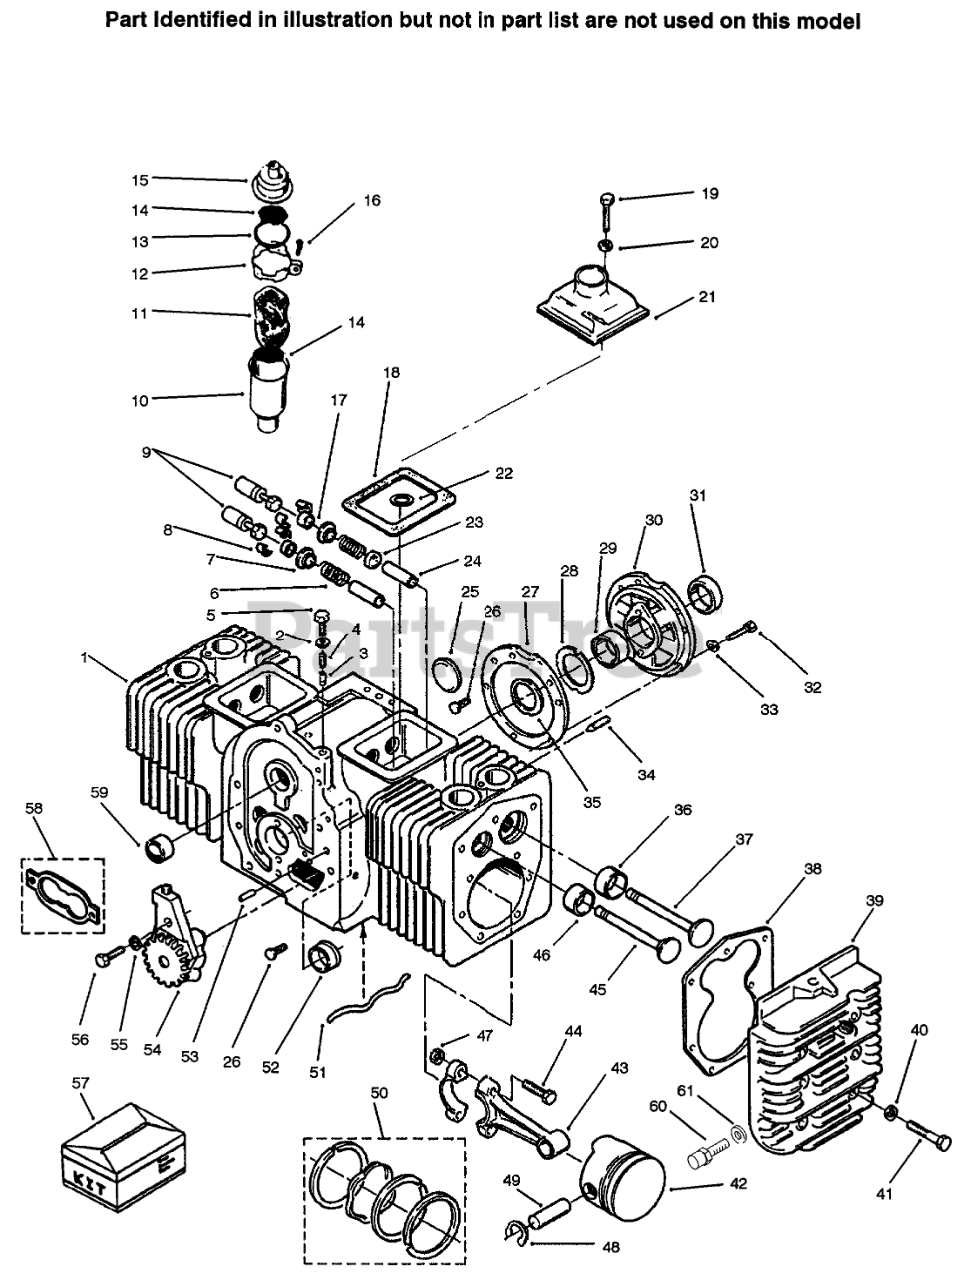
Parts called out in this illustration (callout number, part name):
1	CYLINDER BLOCK
2	WASHER
3	PLUNGER
4	SPRING
5	SCREW-HH
6	VALVE SPRING
7	VALVE SPRING RETAINER
8	VALVE SPRING LOCK
9	TAPPET
9	TAPPET .002 OS
10	TUBE-BREATHER
11	FILTER
12	Clamp
13	SEAL - O-RING
14	SCREEN-BREATHER TUBE
15	BREATHER-CAP AND VALVE
16	SCREW-TAPPING, ROUND HEAD
17	VALVE CAP
18	GASKET
19	HHCS 1/4-20 X 1 3/4
20	WASHER
21	VALVE-COVER L.H.
22	WASHER-FLAT
23	VALVE STEM SEAL
24	EXHAUST VALVE GUIDE
24	INTAKE VALVE GUIDE
26	PIN-DRIVE
27	GASKET
29	BEARING KIT (STANDARD SLEEVE)
29	BEARING KIT (.010)
29	BEARING-CRANKSHAFT (.002)
29	BEARING-CRANKSHAFT (.020)
29	BEARING-CRANKSHAFT (.030)
30	PLATE-BEARING, REAR
32	HEX HD CAPSCREW
33	WASHER-LOCK
33	WASHER-FLAT
34	SCREW-SET
35	WASHER
36	STD INSERT
36	INSERT .010
37	INTAKE VALVE
38	GASKET
39	CYL RS HEAD
39	LH CYLINDER HEAD
40	WASHER
41	Screw-HH
42	STD PISTON KIT
42	PISTON .010
42	PISTON .020
42	PISTON .030
43	CONN ROD ASM
43	ROD .03 US
45	EXHAUST VALVE
46	STD INSERT
46	INSERT .002
46	INSERT .005
46	INSERT .010
46	.025" Oversize
48	Piston Pin
49	PISTON PIN
50	RING/PISTON KIT
50	RING/PISTON KIT .050
50	RING/PISTON KIT .010
50	RING/PISTON KIT .020
50	RING/PISTON KIT .030
51	OIL TUBE
52	KIT-BEARING, SLEEVE
52	BEARING KIT (.010)
52	BEARING-CRANKSHAFT
53	PIN-GEAR COVER
55	WASHER-FLAT
56	SCREW - CAP HEX HEAD
57	ENGINE GASKET KIT
58	GASKET KIT
59	SLEEVE-BEARING
60	HIGH TEMPERATURE
61	WASHER-LOCK EXT TO
